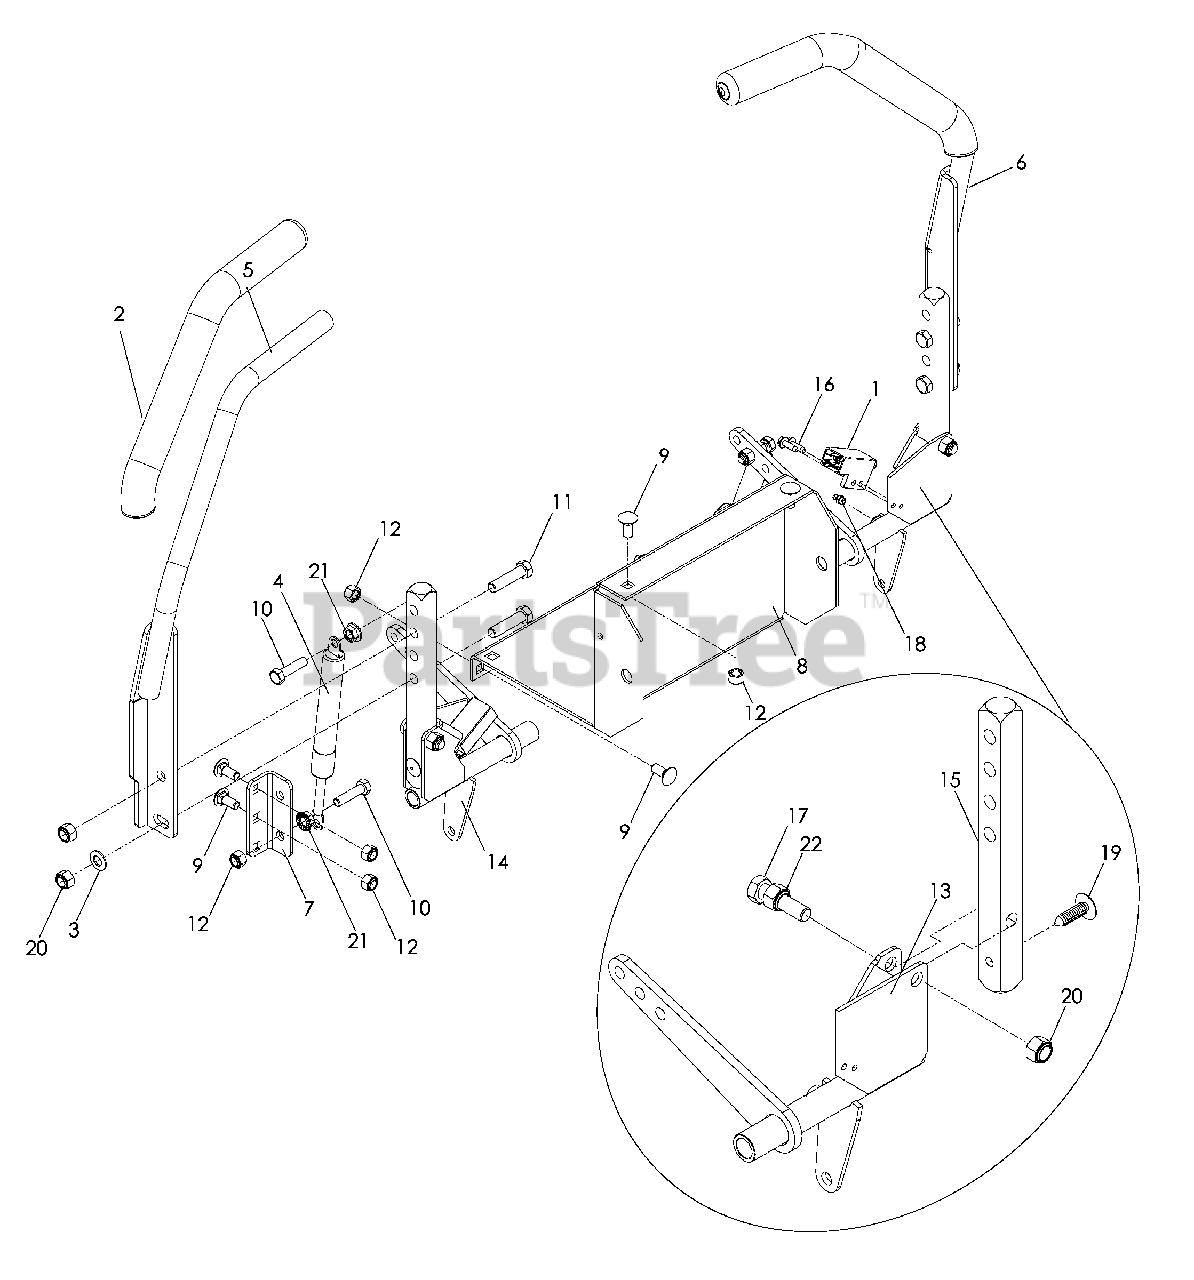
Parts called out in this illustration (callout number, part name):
1	SWITCH, INTERLOCK
2	CUSHION, DRIVE LEVER
3	LOCKWASHER 3/8
5	DRIVE LEVER, RIGHT
6	DRIVE LEVER, LEFT
7	DAMPENER BRACKET
8	BATTERY TRAY
9	RHSNB 5/16-18 x ¾
10	HCS 5/16-18 x 1¼
11	HCS 3/8-16 x 1½
12	NUT 5/16-18 NYLOC
13	CONTROL, LEFT
14	CONTROL, RIGHT
15	CONTROL ARM
16	SCREW 10-24 x 5/8 WASH HD
17	HCS 3/8-16 x 2½ TPBLT
18	ZERK
19	RIVET, NYLON PUSH-IN
20	NUT 3/8-16 NYLOC
21	NUT 5/16-18 WHIZLK
22	NUT 3/8-16 CENTERLOCK
